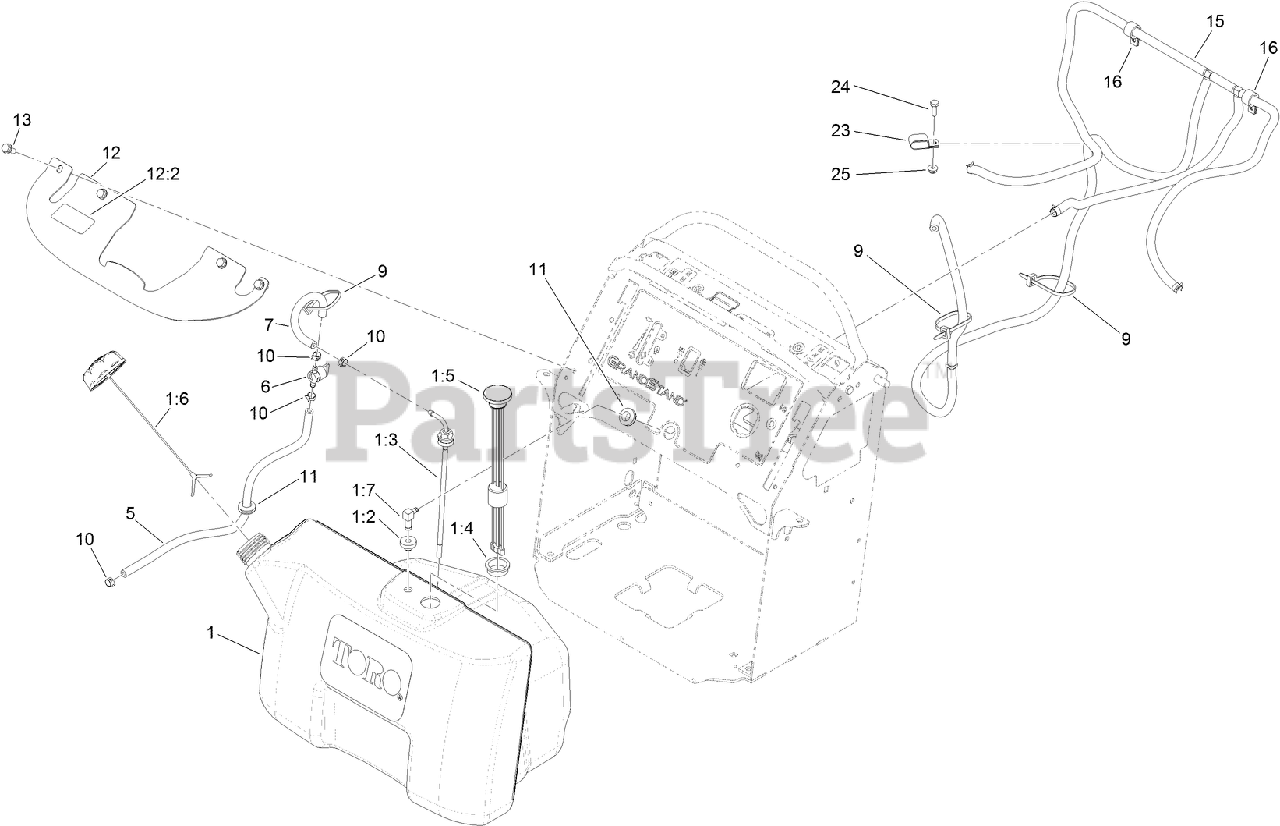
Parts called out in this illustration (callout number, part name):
1	TANK ASM
1:2	BUSHING
1:3	ELBOW-90 DEG
1:4	GROMMET
1:5	GUAGE-FUEL
1:6	CAP-FUEL, RATCHETING
1:7	FITTING-FUEL, BULKHEAD
5	HOSE-FUEL
6	VALVE-FUEL
7	HOSE-FUEL
9	TIE-CABLE
10	CLAMP-HOSE
11	GROMMET
12	BRACKET-TANK
12:2	DECAL-FILL, FUEL
13	SCREW-HWHTF
15	VENT HOSE ASM
16	CLAMP-CABLE
23	CLAMP-TUBE, DOUBLE
24	SCREW-HH
25	NUT-HF
